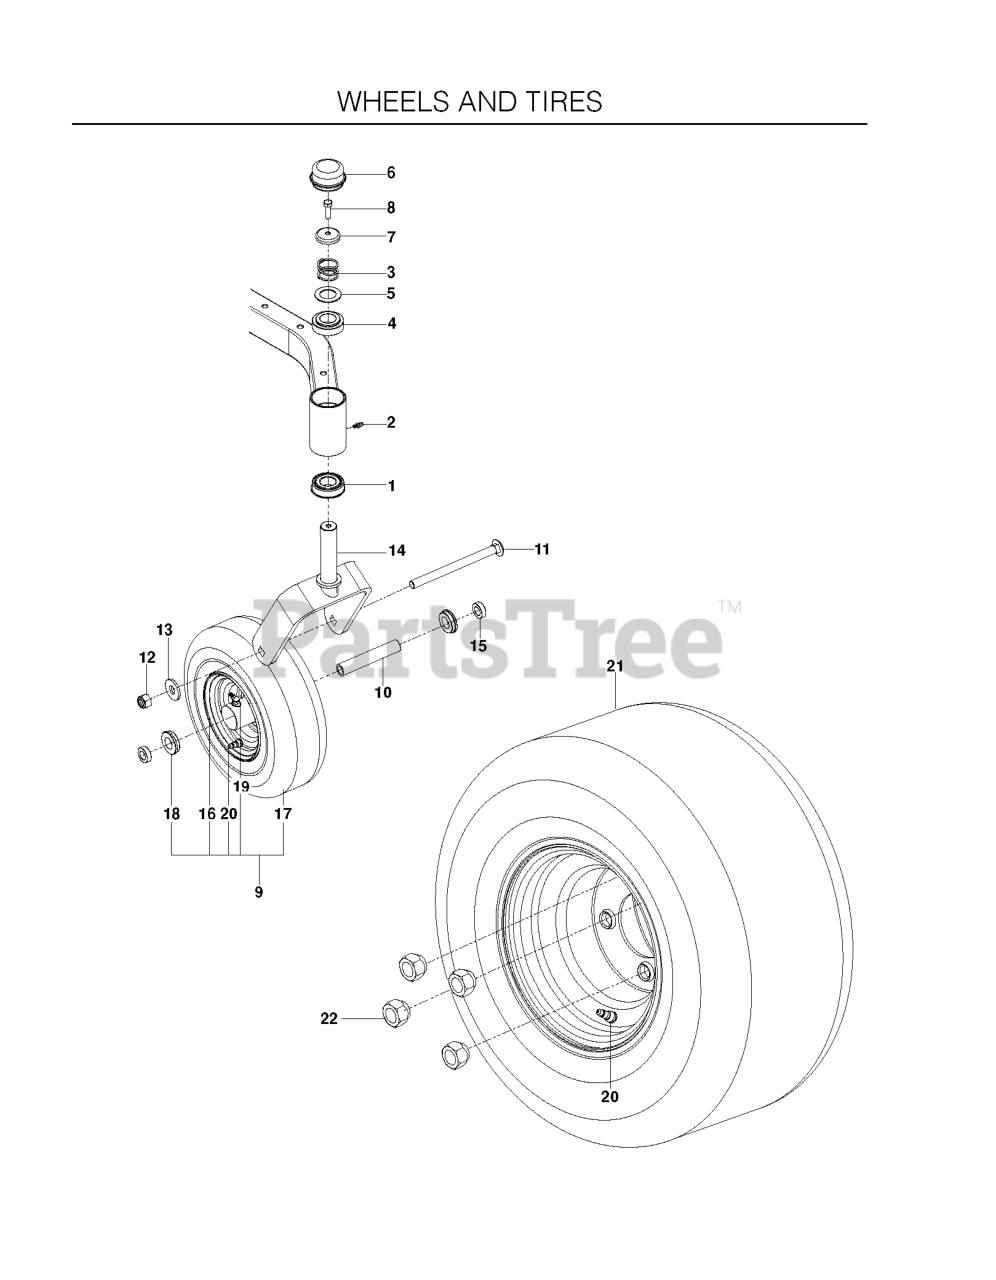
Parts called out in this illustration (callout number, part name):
1	BEARING FLANGED
2	ZERK, 3/16, DRIVE IN
3	SPRING, CASTER
4	BUSHING, CASTER
5	WASHER, 1.025 ID X 1.64
6	GREASE CAP
7	CASTER.PLUG
8	5/16-18X1 HHB G5W/NY
9	TIRE.CASTER.ASSEM.11X4-5.GREY
11	RHSNB 1/2-13 X 6.50 GR2 ZD
12	NUT 1/2-13 HEX NYLOC ZD
13	WASH USS FLAT 1/2
14	CASTER DK BLUE
15	SPACER, 5/16"
17	TIRE.11"X4"-5.4PLY.SMOOTH.KEND
18	BEARING RETAINER
19	ZERK
20	VALVE STEM TR-412
21	RP.WHEEL.ASSEM.18X8.5-8.KENDA.
22	LUG NUT 1/2F
